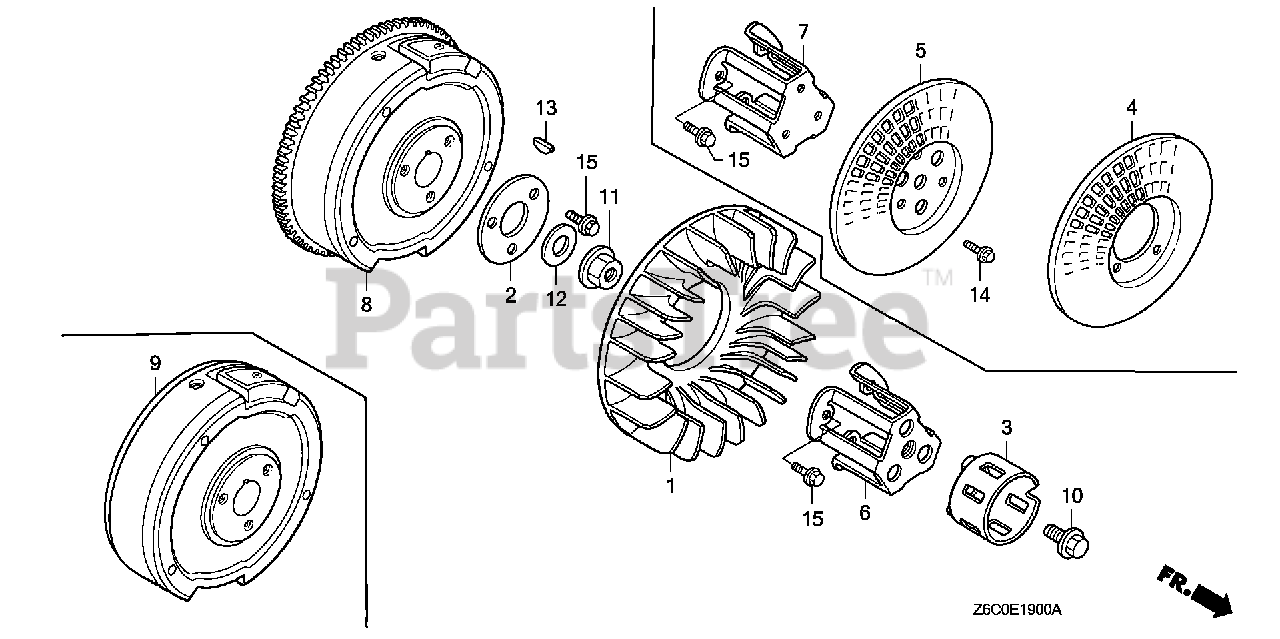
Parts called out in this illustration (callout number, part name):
1	FAN, COOLING
3	PULLEY, STARTER
4	GRID, SCREEN (P.T.O.)
5	GRID, SCREEN (P.T.O.)
6	SPACER, STARTER PULLEY MOUNTING
7	HOLDER, SCREEN GRID
8	FLYWHEEL
10	BOLT, UBS (12X28)
11	NUT, FLANGE (20MM)
12	WASHER (20MM)
13	KEY, SPECIAL WOODRUFF (25X18)
15	BOLT, FLANGE (8X16) Use from Engine SN 1000016.
